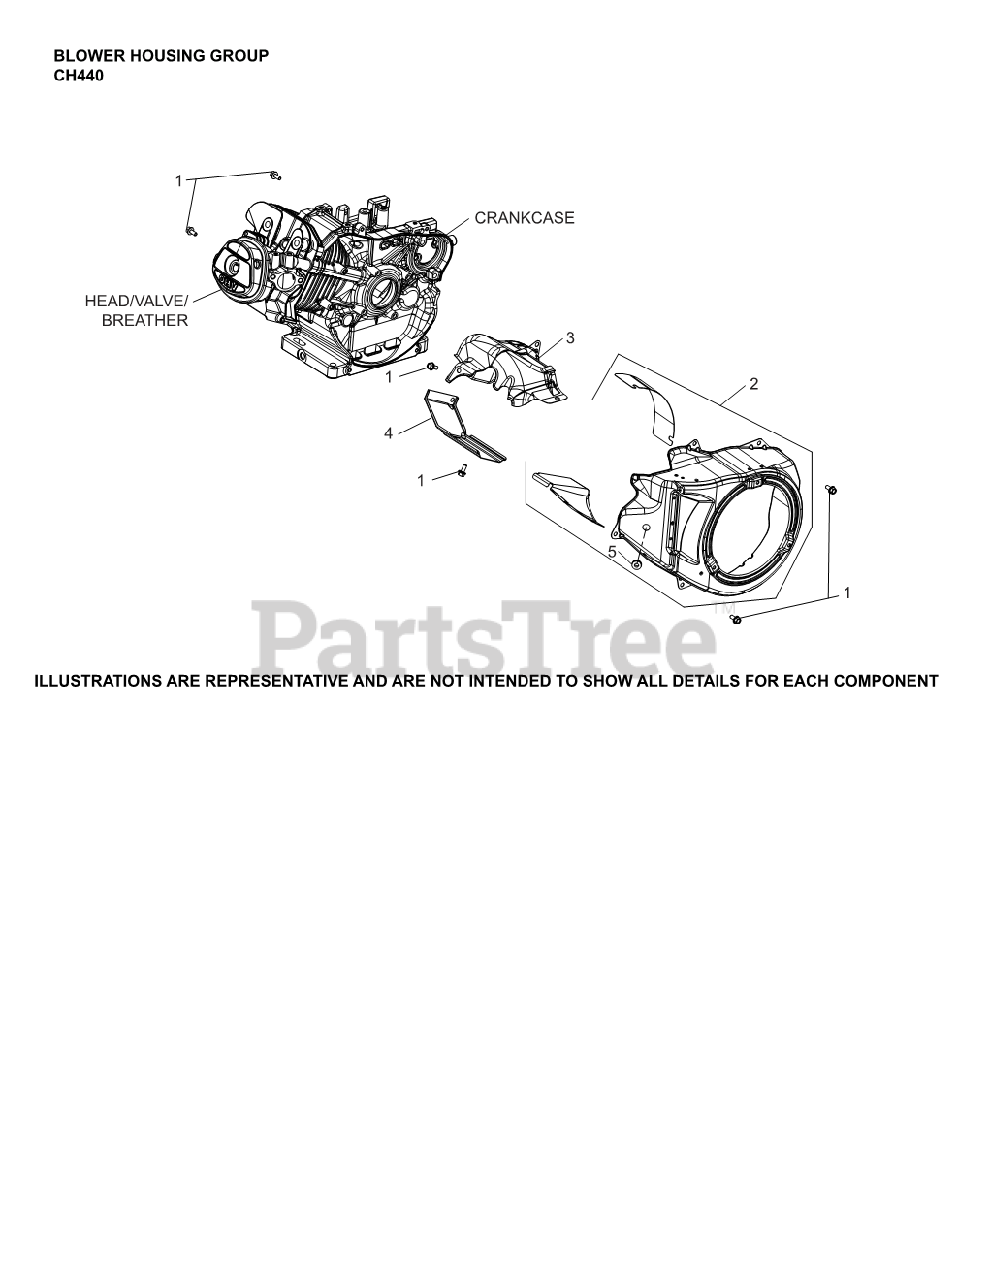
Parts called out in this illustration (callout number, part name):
2	HOUSING, BLOWER ASSEMBLY
3	SHIELD, UPPER HEAT
4	SHIELD, CYLINDER HEAD
5	ISOLATOR, VIBRATION
